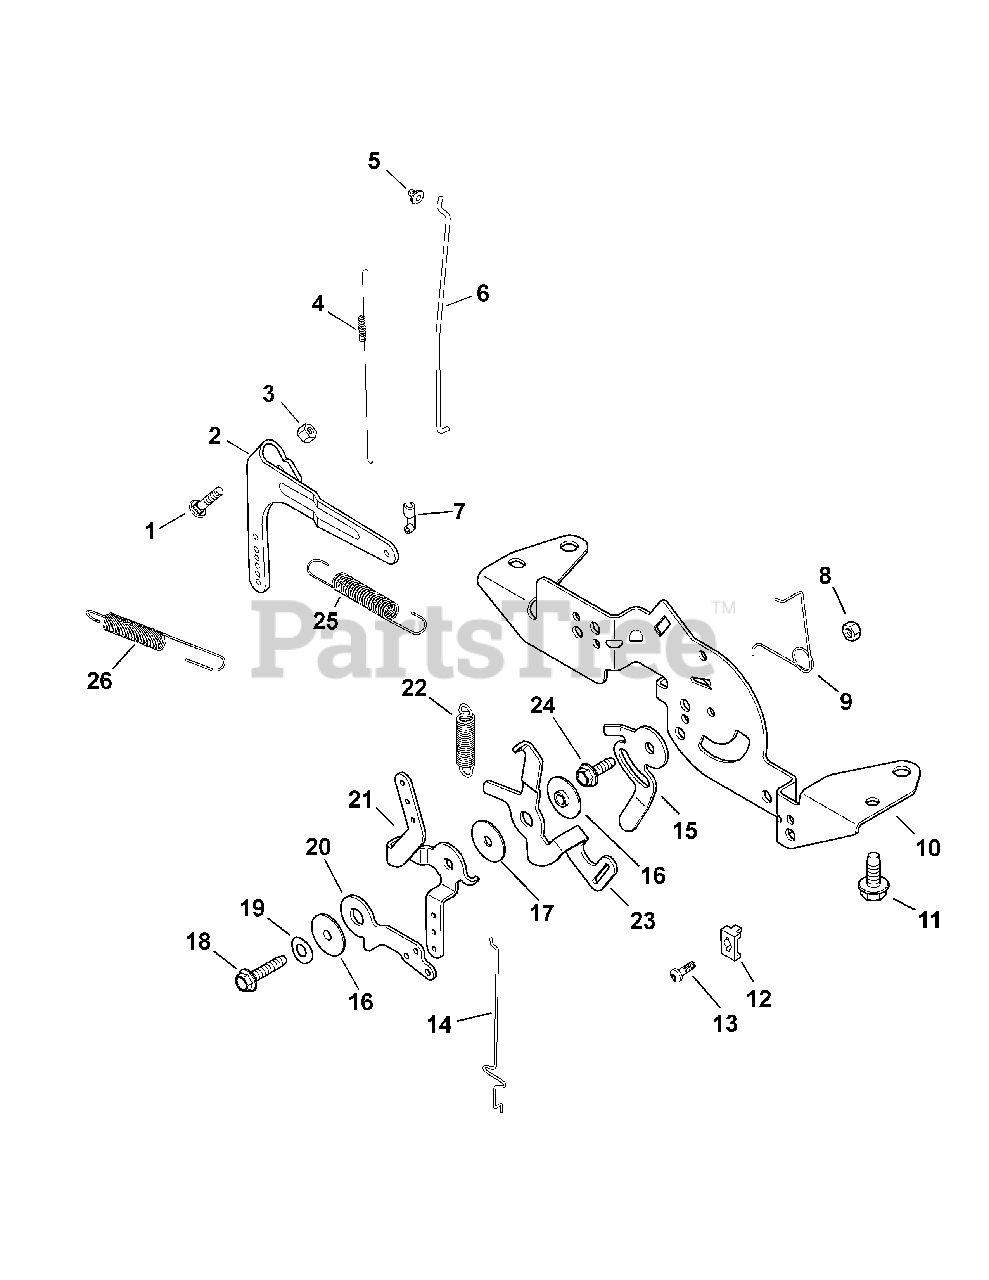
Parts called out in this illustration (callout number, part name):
1	Rd. Hd. Sq. Neck Bolt, M6 x 1.0 x 25
2	Governor Lever
3	Flg. Nut, M6 x 1.0
4	Linkage Spring
5	Linkage Retaining Bushing
6	Throttle Linkage
7	Throttle Linkage Bushing
8	Lock Nut, M5 x .8
9	Choke Return Spring
10	Control Bracket
11	Flg. Thd. Frm. Screw, M6 x 1.0 x 16
12	Cable Clamp
13	Lbd. Thd. Frm. Screw, M5 x 0.8 x 16
14	Choke Linkage
15	Speed Setting Lever
16	Control Assembly Spacer
17	Flat Washer, 5.5MM
18	Thd. Frm. Screw, M5 x 0.8 x 25MM
19	Spring Washer, 1/4"
20	Choke Lever
21	Speed Control Lever
22	Speed Control Spring
23	Governor Spring Lever
24	Flg. Thd. Frm. Screw, M5 x 0.8 x 16
25	Governor Spring
26	Governor Spring
